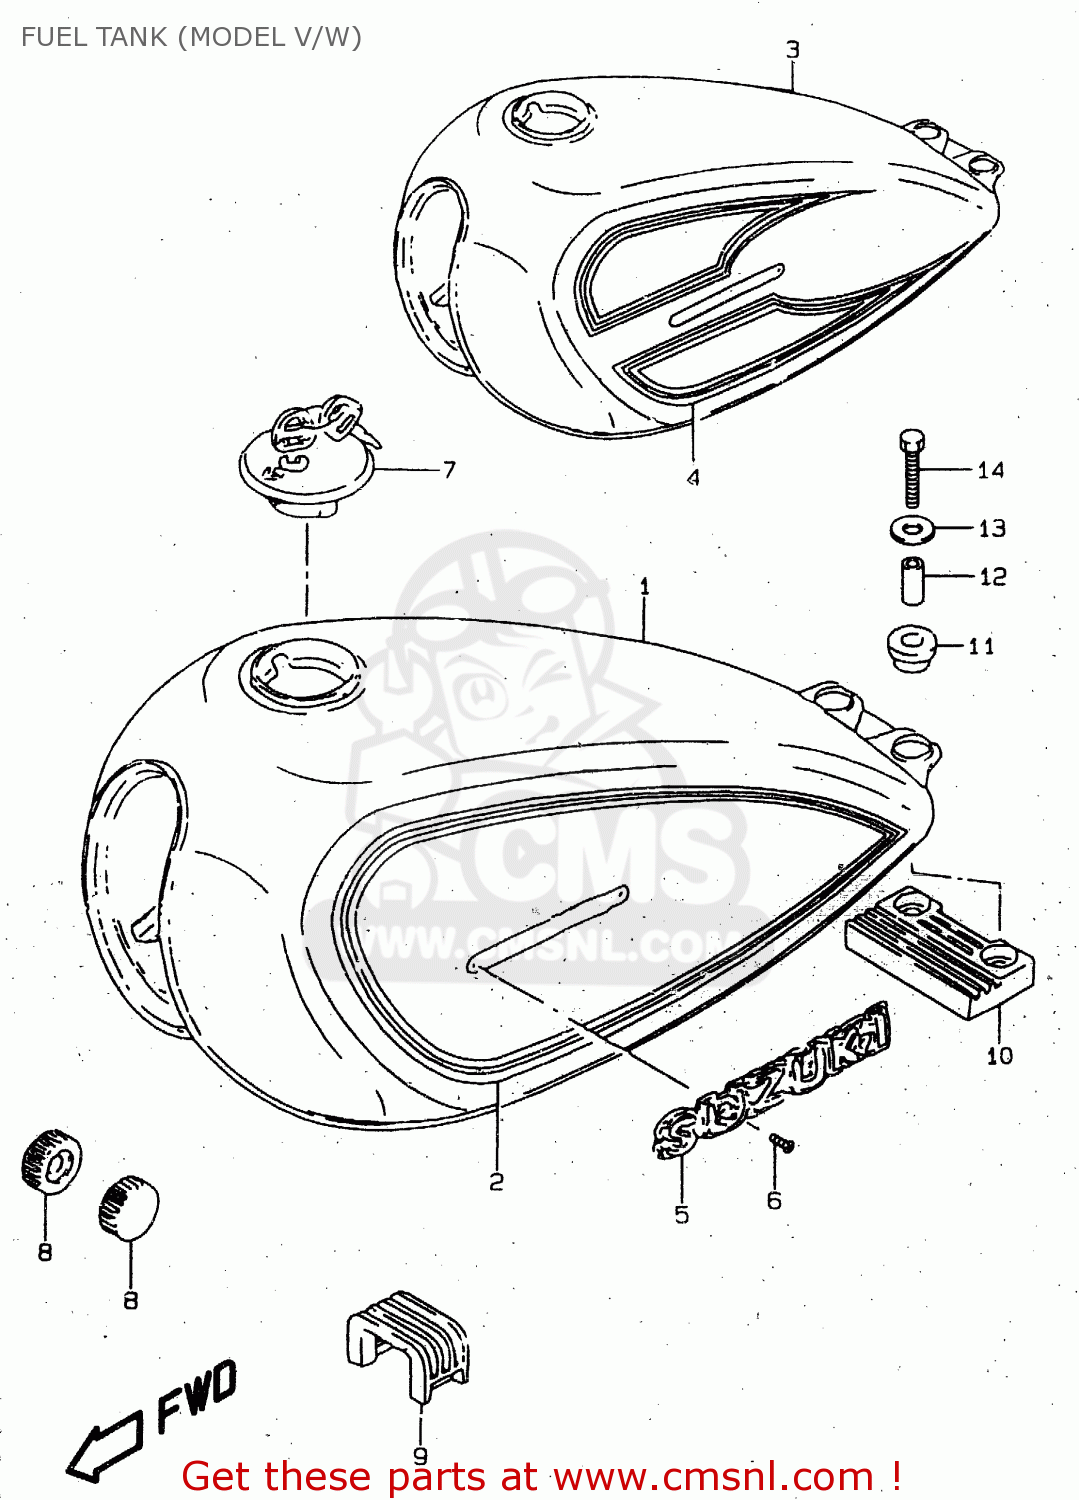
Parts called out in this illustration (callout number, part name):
1	TANK ASSEMBLY,FUEL
2	TAPE SET,FUEL TANK
3	TANK ASSY, FUEL (RED)
4	TAPE SET, FUEL TANK
5	EMBLEM,FUEL TANK
6	SCREW
7	CAP SET,FUEL TANK
8	CUSHION
9	CUSHION,FUEL TANK UPR FR
10	CUSHION,TANK RR NO.1
11	CUSHION
12	SPACER(6.5X10.5X22.5)
13	WASHER(6.5X22X1.6)
14	BOLT(6X35)
